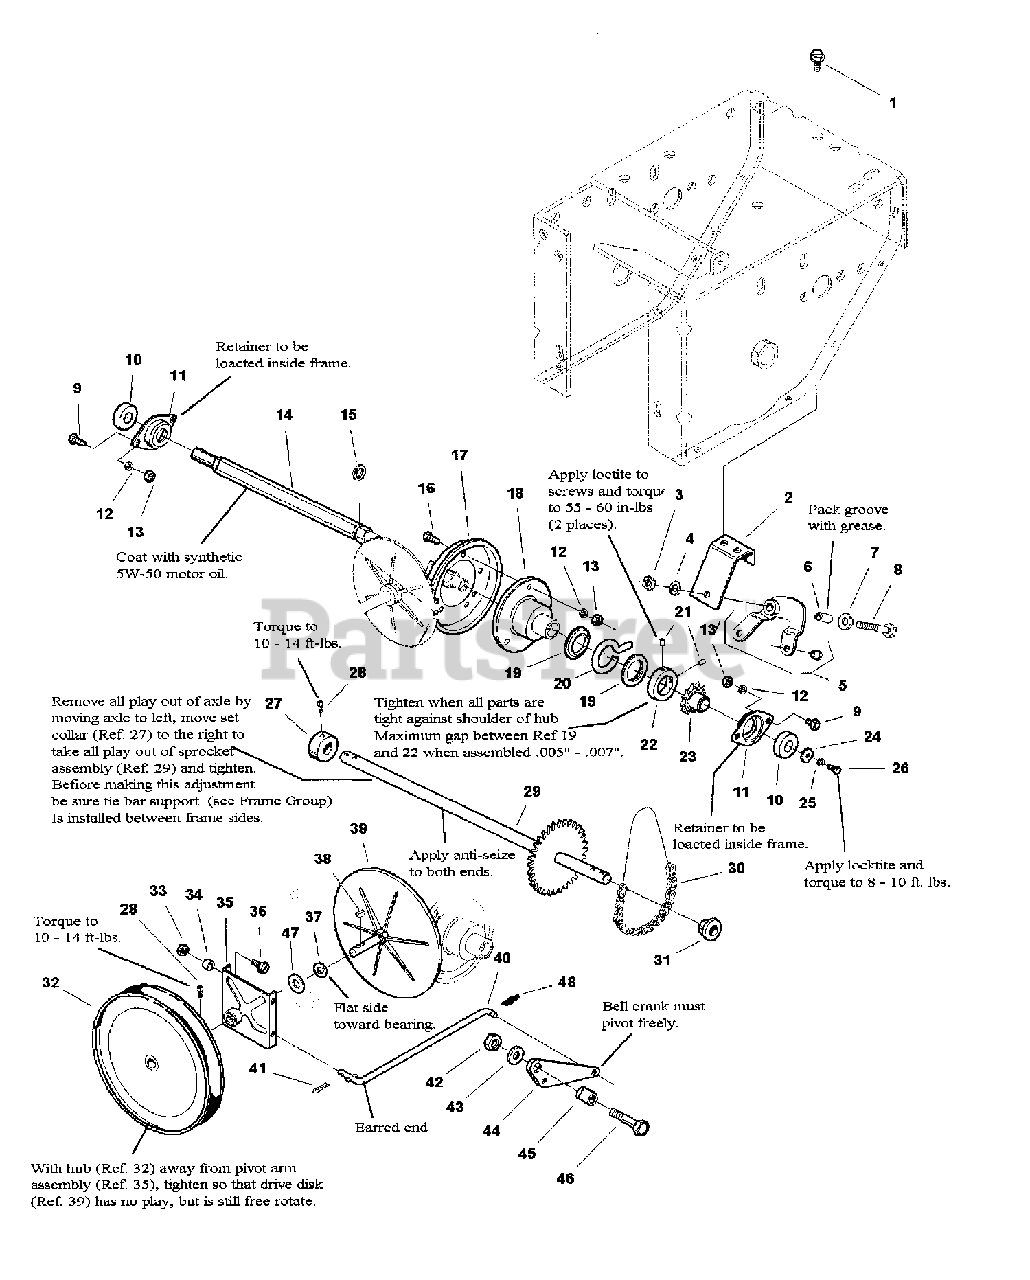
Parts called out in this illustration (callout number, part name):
1	SCREW, 5/16-18 x 5/8" Hex Washer Self-Tap
2	BRACKET, Bushing
3	NUT, 3/8-16 Hex, GR 5 or B
4	WASHER, 3/8" Split Lock
5	ASSEMBLY, Shift Arm w/Bushing
6	BUSHING, Spacer, .380 ID x .750 OD x 1.030 Long
7	WASHER, 3/8" SAE Flat
8	SCREW, 3/8-16 x 2" Hex Head Cap, GR 5
9	SCREW, 5/16-18 x 5/8" Hex Head Cap, GR 5
10	BALL BEARING, .669 ID x .574 OD
11	RETAINER, Bearing
12	LOCKWASHER, 5/16" Spring
13	NUT, 5/16-18 Hex, GR B or 5
14	HEX SHAFT
15	RING, External Retaining (for 3/4 Dia Shaft)
16	SCREW, 5/16-18 x 3/4" Hex Head Cap
17	DRIVEN DISC
18	HUB, Friction Disc
19	COLLAR, Thrust
20	PIN, Slide
21	SET SCREW, 1/4-20 x 1/2 w/Patch Lock
22	COLLAR, Set, 1.251 ID x 2.00 OD x .50 Long
23	SPROCKET #35, 12 Tooth
24	WASHER, 1/4 ID x 5/8 OD x .134/.109 Flat
25	LOCKWASHER, 1/4" Spring
26	SCREW, 1/4-20 x 3/4" Hex Head Cap, GR 5
27	COLLAR, Set, .756 ID x 1.249 OD x .50
28	SET SCREW, 5/16-18 x 1/2" Square Head Cup Point
29	WELDMENT, Axle & Sprocket
30	CHAIN, Roller, #35, 25.5" Long
31	BUSHING
32	PULLEY, Traction
33	NUT, 5/16-18 Large Head Center Lock
34	SPACER, .328 ID x .562 OD x .144/.149 Thick
35	ASSY, Pivot Plate/Hub w/Bearing
36	SCREW, 5/16-18 x 5/8 Hex Head Cap, GR 5
37	WASHER
38	KEY, Hi-Pro, #HP-506
39	DRIVE DISC, w/ Spindle
40	ROD, Pivot
41	COTTER PIN, 1/8 x 3/4"
42	NUT, 5/16-18 Hex Nyloc Light
43	WASHER, .312 (.34 ID x .75 OD)
44	BELLCRANK
45	BUSHING
46	SCREW, 5/16-18 x 1-3/4 Hex Head Cap, GR 5
47	WASHER, Plain, .75 ID x 1.31.OD x .10
48	COTTER PIN, 3/8" Self Lock
